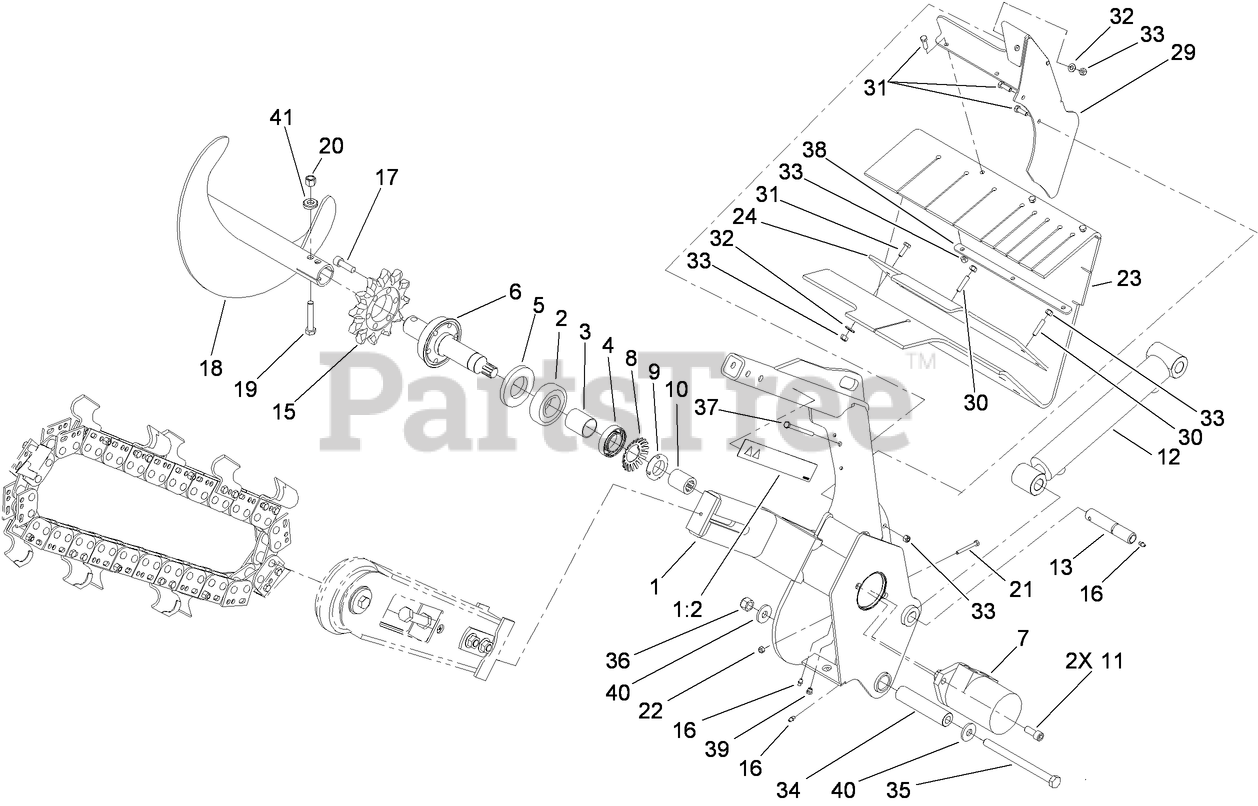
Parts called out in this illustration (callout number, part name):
1	TRENCHER HEAD ASM
1:2	DECAL-DANGER
2	BEARING-BALL
3	SPACER
4	BEARING-BALL
5	SEAL-GREASE
6	SHAFT-TRENCHER
7	MOTOR-HYD
8	LOCKWASHER-BEARING
9	LOCKNUT-BEARING
10	SPLINE-COLLAR
11	SCREW-HSH
12	HYD CYLINDER ASM
13	PIN-PIVOT
15	SPROCKET-TRENCHER
16	FITTING-GREASE
17	SCREW-HSH
18	AUGER-TRENCHER
19	SCREW-HH
20	NUT-LOCK, NI
21	SCREW-HH
22	NUT-LOCK, NI
23	SHIELD-DIRT
24	BAR-CLAMP
29	BRACKET-SHIELD
30	SCREW-HSH
31	SCREW-HH
32	WASHER-FLAT
33	NUT-LOCK, NI
34	SPACER-PIVOT
35	BOLT-HH
36	NUT-LOCK, NI
37	SCREW-HH
38	PLATE-STRAP, SHIELD
39	FITTING-LUBE
40	WASHER-HARDENED
41	WASHER-SADDLE
